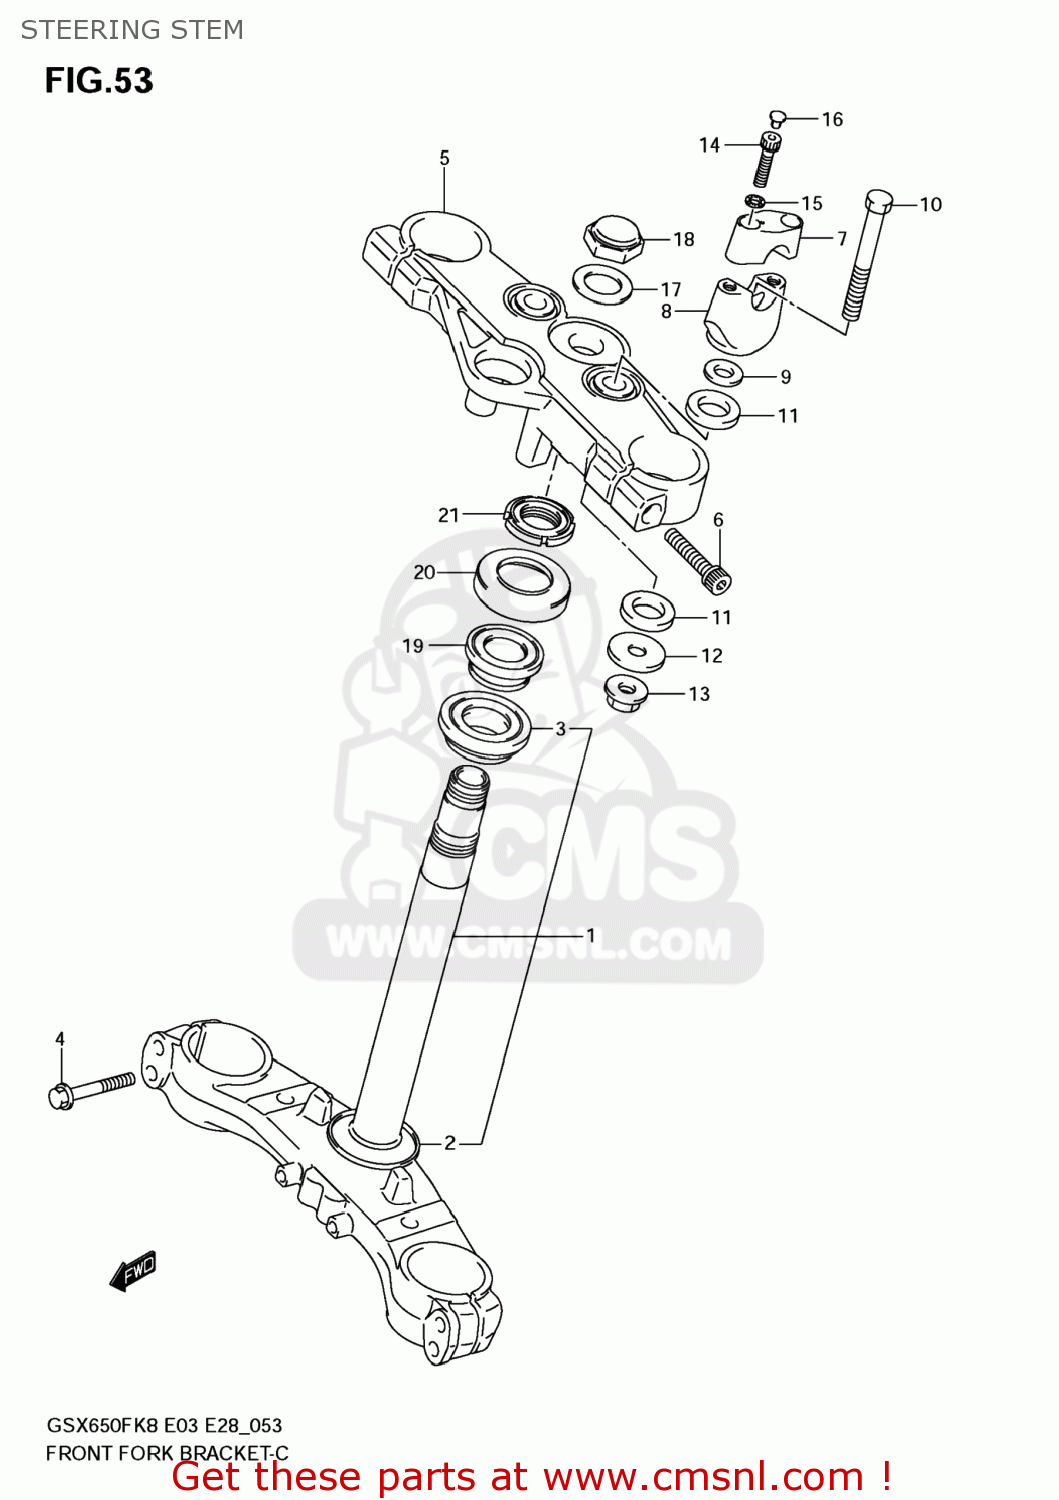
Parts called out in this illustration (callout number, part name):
1	BRACKET,UNDER
2	SEAL,STEERING LWR
3	BEARING(30X55X17)
4	BOLT
5	BRACKET,UPR
6	BOLT
7	HOLDER,HANDLE
8	HOLDER,HANDLE UNDER
9	WASHER
10	BOLT
11	RUBBER,HANDLE HOLDER
12	WASHER
13	NUT
14	BOLT,STEM HEAD
15	WASHER
16	CAP(OD:11)
17	WASHER(22.5X35.9X1.6)
18	NUT,CAP
19	BEARING(25X47X15)
20	DUST SEAL,STEERING UPR
21	NUT,STEERING STEM
